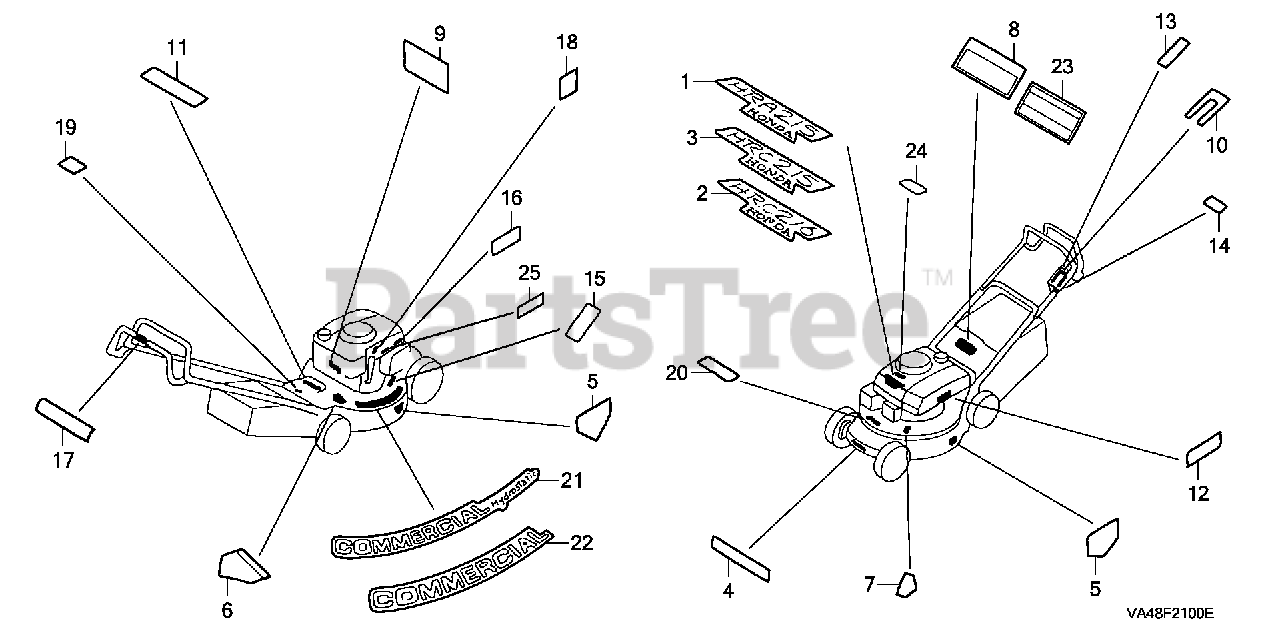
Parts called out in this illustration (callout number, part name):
1	MARK, EMBLEM
4	LABEL A, HOUSING CAUTION (ENGLISH)
5	LABEL B, HOUSING CAUTION (ENGLISH)
5	LABEL C, HOUSING CAUTION
6	LABEL C, HOUSING CAUTION
7	LABEL, STEP POSITION (ENGLISH)
8	LABEL, WARNING (ENGLISH)
9	LABEL, FUEL WARNING (B)(ENGLISH)
11	MARK, CHANGE INDICATION
12	MARK, AIR CLEANER CAUTION (ENGLISH)
13	MARK, THROTTLE (ENGLISH)
17	MARK, BLADE CONTROL (ENGLISH)
18	MARK, OIL CAUTION
19	MARK, TYPE (SXA)
20	MARK, TYPE (SX)
